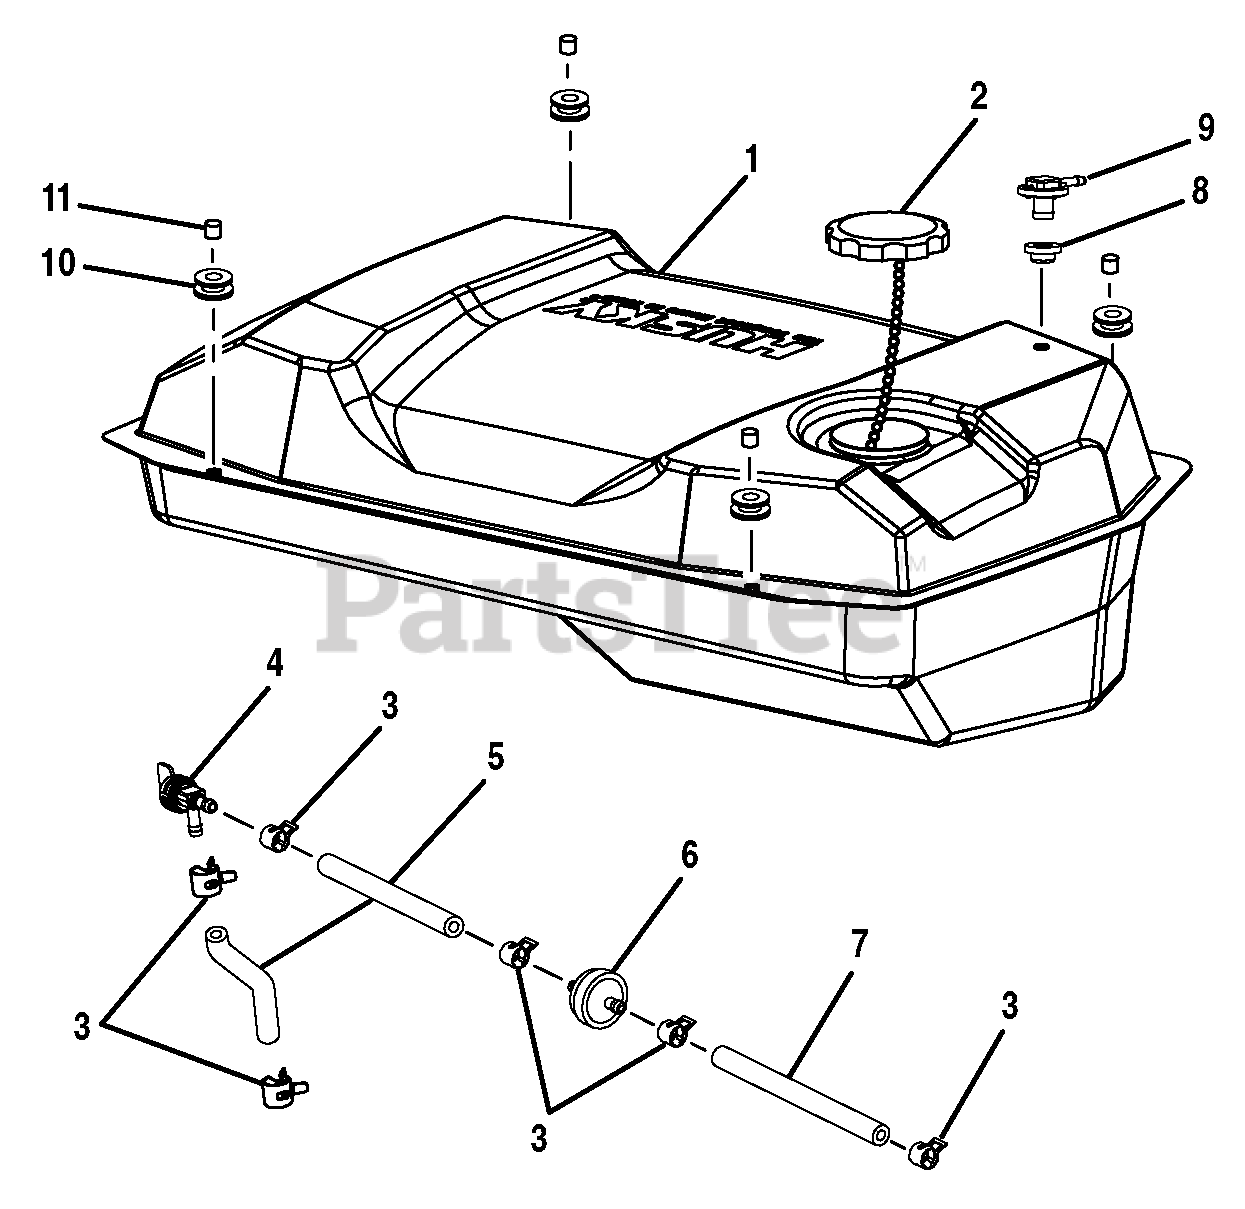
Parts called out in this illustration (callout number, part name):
1	Fuel Tank
2	Fuel Tank Cap
3	Fuel Line Clamp (1/2 in.)
4	Fuel Shut Off Valve
5	Fuel Line (6.4 mm x 72 mm)
6	Fuel Filter
7	Fuel Line (6.4 mm x 144 mm)
9	Rollover Valve
10	Bushing (Fuel Tank Isolator)
11	Spacer (Fuel Tank Isolator)
